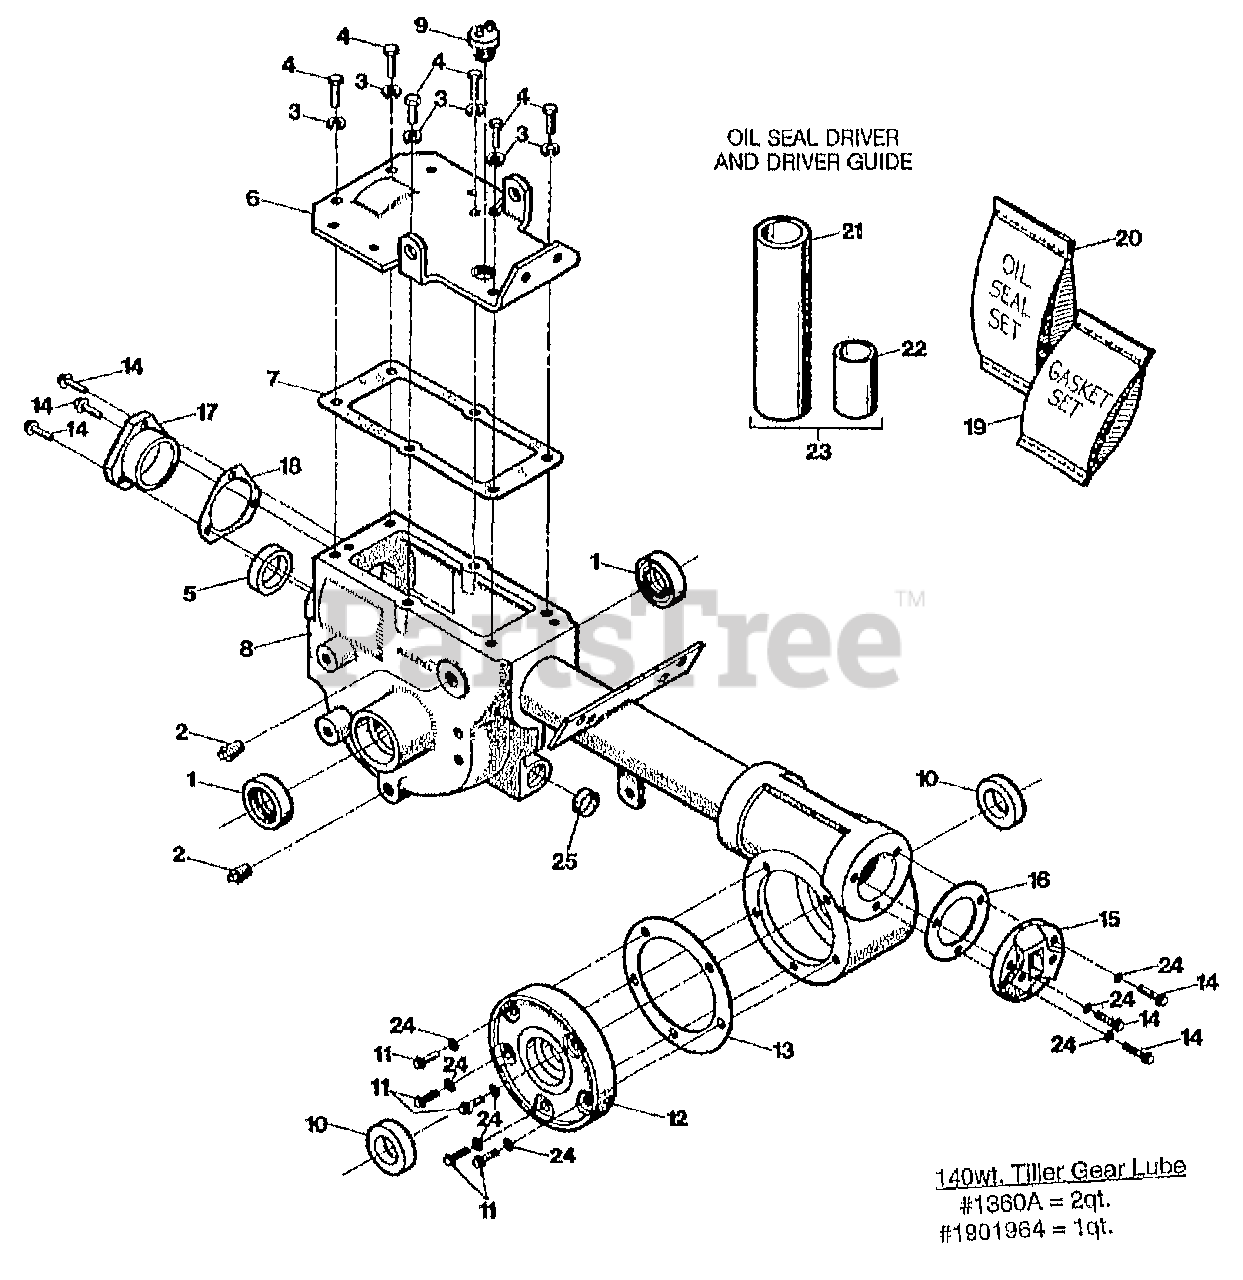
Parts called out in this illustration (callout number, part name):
1	SEAL-OIL WHEELSHAFT (Double lip, wheel shaft, RT & LT sides.)
2	PLUG-PIPE 1/4 NPT (Oillevel hole and gear oil drain hole.)
3	WASHER-LK .312 ZP (Transmission top cover)
4	SCR-HHC 5/16-18X.75 GR 5 ZP (Transmission top cover)
5	SEAL-PINION SHAFT PT/85030/00 (Input pinion shaft, front of transmission)
6	COVER-TRANS (Top of Transmission)
7	GASKET-TRANS COVER
8	HSG-TRANS P5 A UNIT (Inc. #9429 rear bearing race)
9	PLUG-OIL FILL 3/4-10 (For gear oil fill hole on transmission cover.)
10	SEAL-TILLER SHAFT (LT & RT sides.)
11	SCR-HH 1/4-20X.625
12	COVER-RTH W/SCRS & RACE
13	GASKET-TILLER COVER (Fits all covers)
14	SCR-HFLK 1/4-20X.875
15	CAP-REAR #1115
16	GASKET-BRG COVER
17	COVER-FRONT BEARING
18	GASKET-FRONT COVER-.010
19	GASKET SET-P4 (Inc. 1 #7, 1 #18, 2 # 13, 1 1129-2 .030", 2 #16)
20	OIL SEAL SET-PONY V (Inc. 2 #1, 2 #10, 1 #50)
21	DRIVER-PLASTIC (For wheel shaft & tiller shaft oil seals.)
22	SEAL-DRIVER PILOT (To install wheel shaft & tiller shaft oil seals.)
23	KIT-DRIVER (Inc. 21 & 22)
24	WASHER - Nylon, not reusable
25	PLUG-BORE (For bore hole directly beneath the front of the transmission tube.)
